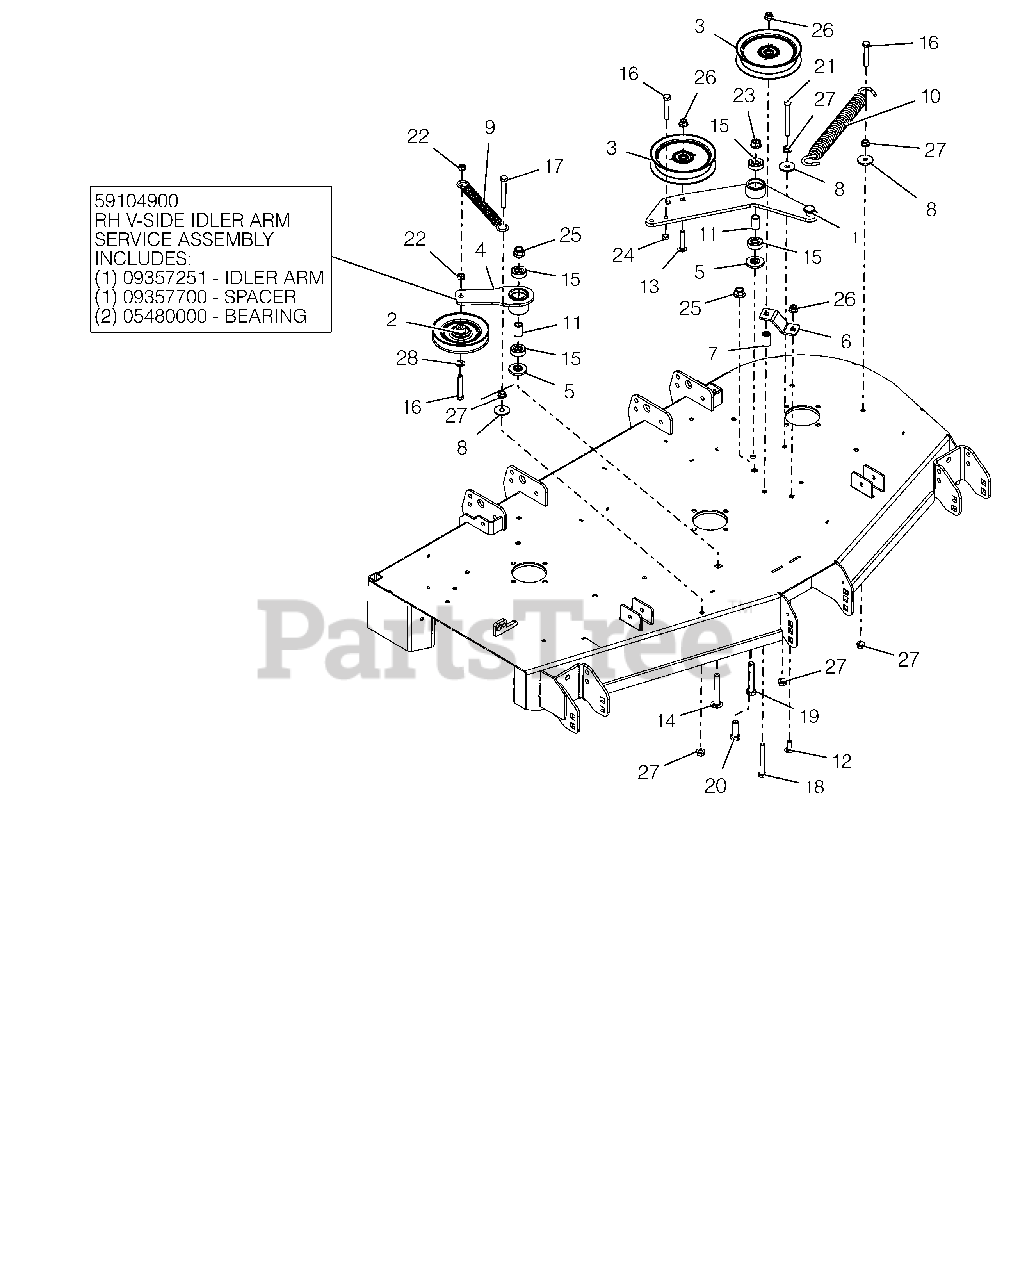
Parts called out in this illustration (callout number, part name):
1	DECK PTO IDLER ARM WLDMT - BLK
2	IDLER, V-5.00"
3	IDLER, FLAT 5.00"
4	DECK RH IDLER ARM WMT - BLK
4	RH V-SIDE IDLER ARM ASSEMBLY
4	SPACER .510 X .75 X 1.1485
4	BRG-BALL .50X1.38X.438 SEALED
5	SPACER, IDLER ARM
6	PTO FIXED IDLER MTG BRKT -RED
7	BUSHING, SLV .380X.750X1.190
8	WSHR-FL-STL .406X1.375X.135 YZ
9	SPRING, EXTENSION
10	SPRING, EXTENSION
11	SPACER .510 X .75 X 1.1485
12	@BLT-RDHDSHSQNK.38-16X1.0 G5YZ
13	BLT-RDHDSQNK .38-16X2.00 SHTYW
14	BLT,RDHDSQSHNK.50-13X3.25 G5YZ
15	BRG-BALL .500X1.38X.437
16	@BLT-HEX .38-16X2.25 GR5 YWZC
17	@BLT-HEX .38-16X3.00 GR5 YWZC
18	@BLT-HEX .38-16X3.25 GR5 YWZC
19	@BLT-HEX .50-13X3.00 GR5 YWZC
20	@BLT-HEX .50-13X1.50 GR5 YWZC
21	@BLT-HEX .38-16X3.50 GR5 YWZC
22	@NUT-LK-CTR .38-16 YWZC
23	NUT-LK-CTR-FLG .50-13 YWZC
24	NUT-HEX-JAM .375-16 YWZC
25	@NUT-LK-NYL-FLG .50-13 YWZC
26	@NUT-LK-NYL-FLG .38-16 YWZC
27	@NUT-SPNLK-FLG .375-16 YWZC
28	@WSHR-FL-STL.406X.812X.065 YWZ
